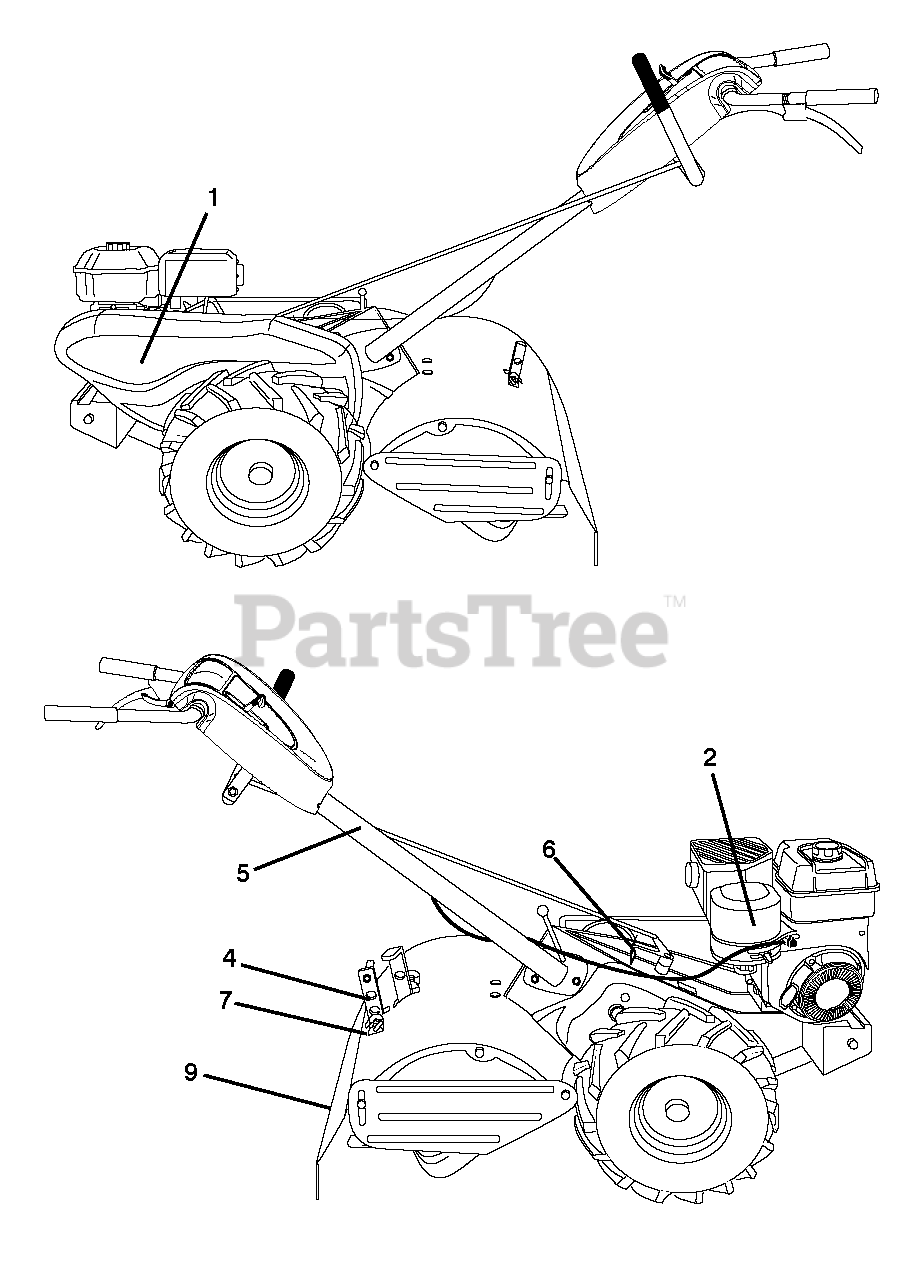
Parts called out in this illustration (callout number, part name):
1	RP.DECAL.BADGE.170MM.TEXTLOGO
2	DECAL.B&S.950S
4	DECAL.TINE.SHIELD.CRT.17".HUSQ
5	DECAL TI (2 2)
6	DECAL.SHIFT.INDICATOR.TILLER
7	DECAL.WARNING.SHLD.ENG/FR
9	DECAL TI
